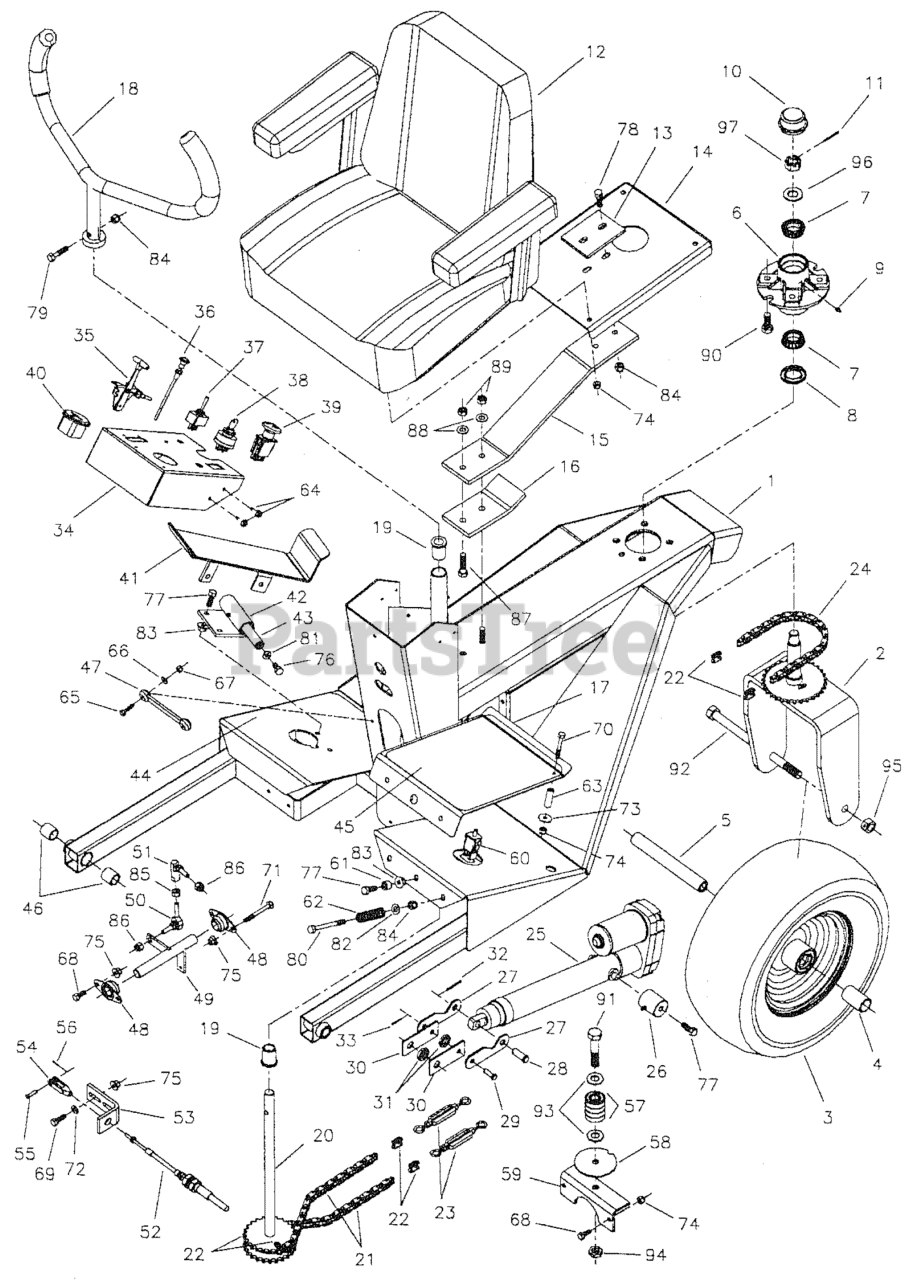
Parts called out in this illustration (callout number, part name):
1	Trailer Weldment
2	Mount, Steering Tire
3	Tire, Steering
4	Spacer, Axle
5	Axle, Steering Tire
6	Hub, Steering
7	Bearing, Tapered Roller
8	SEAL, GREASE
9	Grease Fitting
10	Cap, Dust
11	PIN, COTTER, 1/8 X 1-1/4
12	SEAT, GRAY, NO LOGO, CMPT
13	Support, Seat Plate
14	Plate, Seat
17	Plate, Operator Presence
18	Steering Handle Assembly
18	Grip, Foam
18	Collar, 1 Split
19	Bushing, Flange
20	Shaft, Steering Sprocket
21	Chain, Roller - 31 Links
22	Connector, Chain Link
23	Turnbuckle
24	Chain, Roller - 35 Links
25	Actuator, Electric Lift
26	Mount, Actuator
27	Link, Actuator Lower
28	Pin, Clevis
29	Pin, Clevis
30	Link, Actuator
31	Spacer, Blade
32	PIN, COTTER, 1/8 X 1-1/4
33	PIN, 3/32 X 0.750, COT, ZINC/CLEAR
35	Cable, Throttle
36	CABLE, CHOKE CONTROL, 45
37	Switch, Actuator
38	SWITCH, IGNITION, 6 POST
39	SWITCH, BLADE ENGAGEMENT
40	Hour Meter
41	Pedal, Foot Control
41	Safety Walk
42	Mount, Foot Pedal
42	Bushing, Brass
43	Shaft, Pedal Pivot
44	Safety Walk -Right
45	Foot Plate Safety Walk
46	Bushing, Plastic
47	Strap, Rubber
48	Bearing, Bronze Flange
49	Bell Crank
50	Ball Joint, 3/8 Male Studded
51	Ball Joint, 3/8 Female Studded
52	Cable, Speed Control
53	Bracket, Cable
55	Pin, Clevis
56	Pin, Cotter
57	Bearing, Roller
58	Washer, Chain
59	Mount, Chain Roller
60	Switch, Plunger, Snap-In
61	Insert, Bearing
62	Spring, Compression
63	Bushing, Brass
64	Bolt, 1/4-20 x 3/4 SelfTapper
65	BOLT, 1/4-20 X 1" GD5 CZ
66	WASHER, 1/4 SAE
67	NUT, 1/4-20 HEX NYLON LOCK
68	BOLT, 5/16-18 X 3/4 GD5
69	Bolt, 5/16-18 x I GD.5
70	Bolt, 5/16-18 x 2 GD5
71	Bolt, 5/16-18 x 2-1/2 GD.5
72	WASHER, 5/16" SAE
73	Washer, 5/16 Fender
74	Nut, 5/16-18 Hex Nylon Lock
75	NUT, 5/16-18 HEX SERRATED FLANGE (LARGE)
76	BOLT, 3/8-16 X 3/4" GD5 CZ
77	BOLT, 3/8-16 X 1" GD5 CZ
78	BOLT, 3/8-16 X 1-1/4" GD5 CZ
79	BOLT, 3/8-16 X 1-1/2" GD5 CZ
80	BOLT, 3/8-16 X 3-1/2" GD5 CZ
81	Washer, 3/8 Lock
82	WASHER, 3/8 SAE
83	Nut, 3/8-16 Serrated Flange
84	NUT, 3/8-16 HEX NYLON LOCK
85	Nut, 3/8-24 Hex
86	Nut, 3/8-24 Hex Nylon Lock
87	Bolt, 7/16-20 x 1-3/4 GD.8
88	Washer, 7/16 SAE
89	Nut, 7/16-20 Hex Nylon Lock
90	BOLT, 1/2-20 X 1-1/4" GD5 CZ
91	BOLT, 5/8-11 x 3" GD5 CZ
92	Bolt, 5/8-11 x 9-1/2 GD.5 Plain
93	Washer, 518 SAE
94	Nut, 5/8-11 Hex Nylon Jam
95	Nut, 5/8-11 Hex Side Lock
96	WASHER, 3/4 SAE
97	Nut, 3/4-16 Hex Slotted
